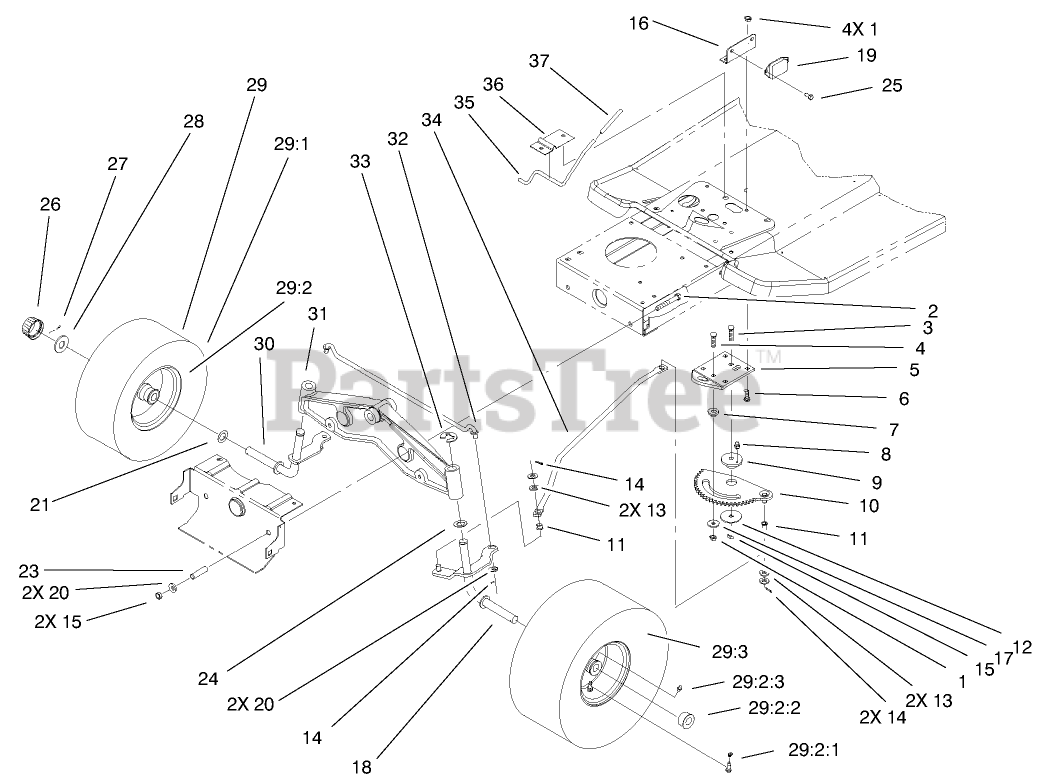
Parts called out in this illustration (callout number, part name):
1	NUT-LOCK, NI
2	SCREW-HH
3	SCREW-CARR
4	SCREW-CARR
5	BRACKET-RACK, STEERING
6	BOLT-CARR
7	SPACER-RACK, STEERING
8	FITTING-GREASE
9	BUSHING-ECCENTRIC
10	RACK-STEERING
11	BUSHING-FLANGED, NYLON
12	WASHER-BEARING
13	WASHER-FLAT
14	PIN-COTTER
15	NUT-LOCK, NI
16	BRACKET-MODULE
17	WASHER-PIVOT
18	LH SPINDLE ASM
19	MODULE
20	WASHER-FLAT
21	WASHER-THRUST
23	SPACER
24	WASHER-THRUST
25	SCREW-HWH
26	CAP-HUB
27	PIN-COTTER
28	WASHER-PLAIN
29:2:2	BEARING-WHEEL
29:2:3	FITTING-GREASE
30	RH SPINDLE ASM
31	FRONT AXLE ASM
32	TIE ROD-STEERING
33	E-RING
34	LINK-DRAG
35	ROD-BRAKE, PARKING
36	BRACKET-PARKING BRAKE
37	GRIP-BRAKE, PARKING
